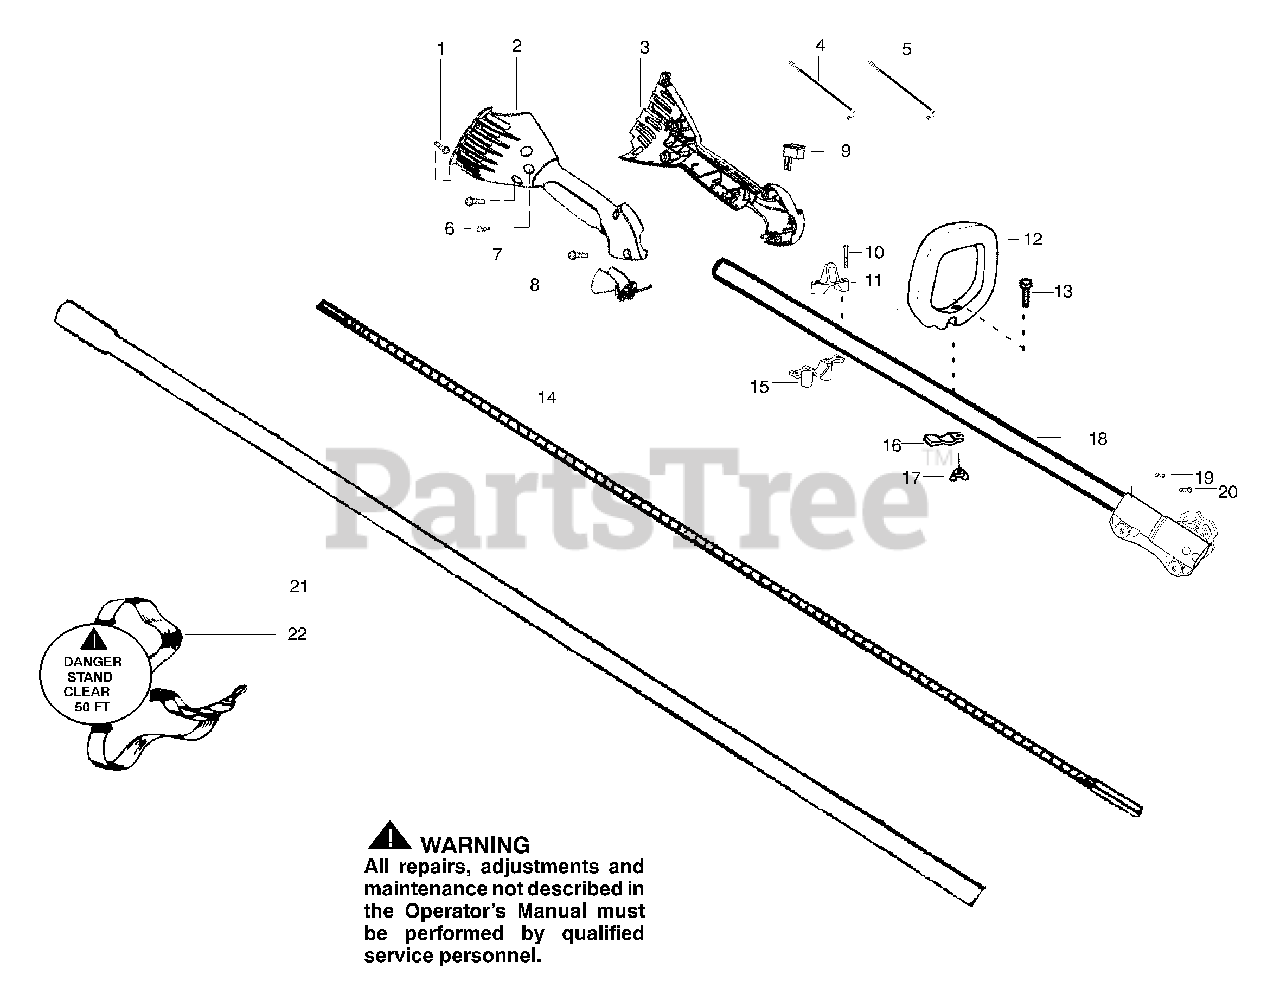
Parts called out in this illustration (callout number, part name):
2	Hsg.-Throttle right
3	Hsg.-Throttle left
4	Assy-Wire
5	Assy-Upper Wire
6	Screw-Align
9	Kit-Switch
11	Clamp-Upper
12	Assy-Handle
14	Flex-Lower
15	Clamp-Lower
16	Clamp-Handle
17	Wingnut
18	Kit-Upper Shaft
20	Screw-Alignment
21	Assy-Driveshaft
22	Assy-Shoulder Strap
